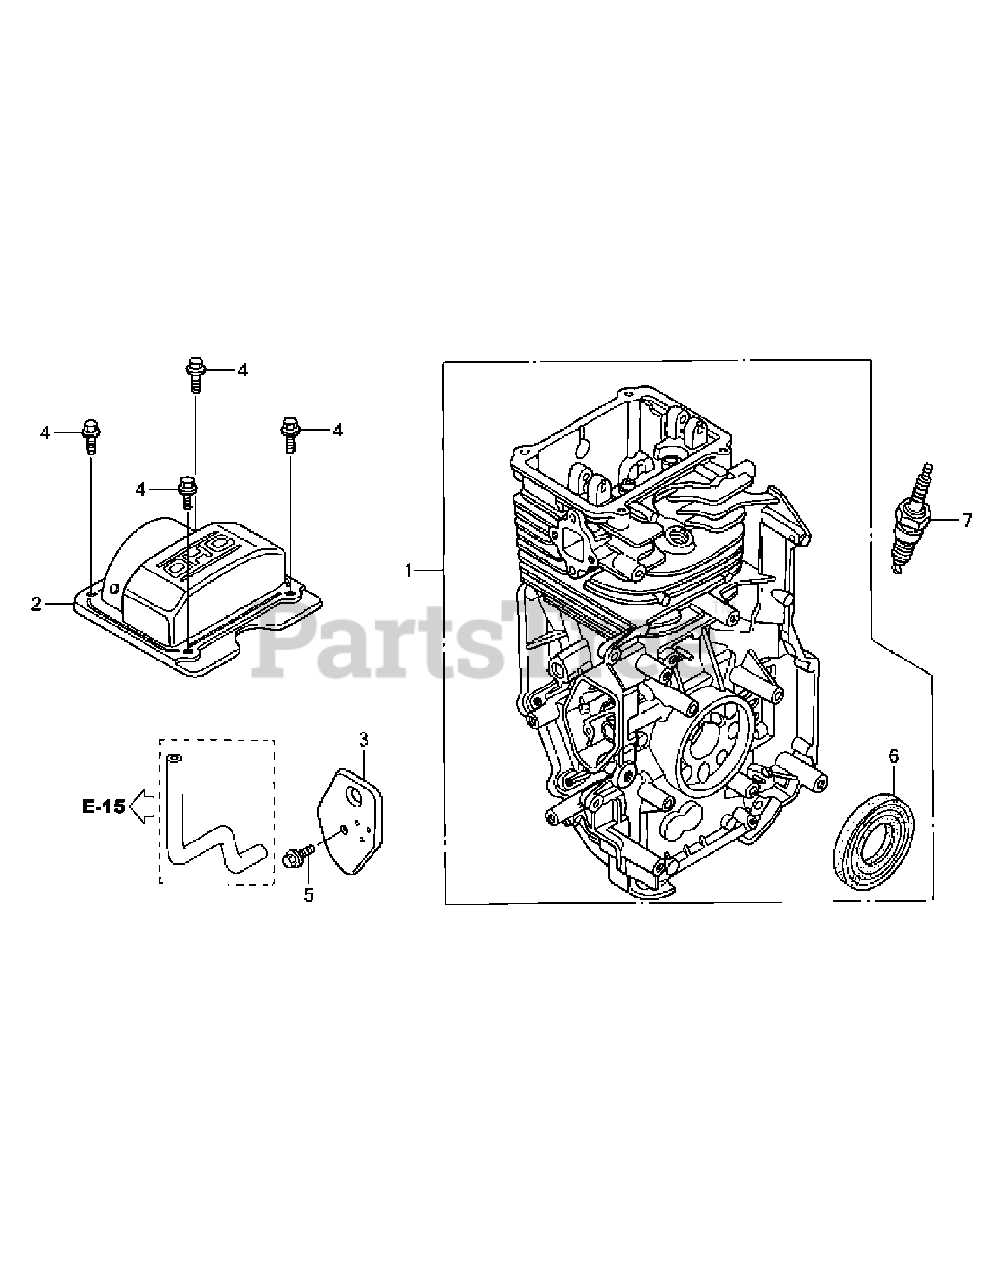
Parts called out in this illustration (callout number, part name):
1	Barrel Assy., Cylinder
2	Cover Comp., Cylinder Head
3	Cover Comp., Breather
4	Bolt, Flange, 6X12 (Ct200)
5	Bolt, Flange, 6X14 (Ct200)
6	Oil Seal, 25.4X62X6
7	Plug, Spark (Bpr6Es) (Ngk)
